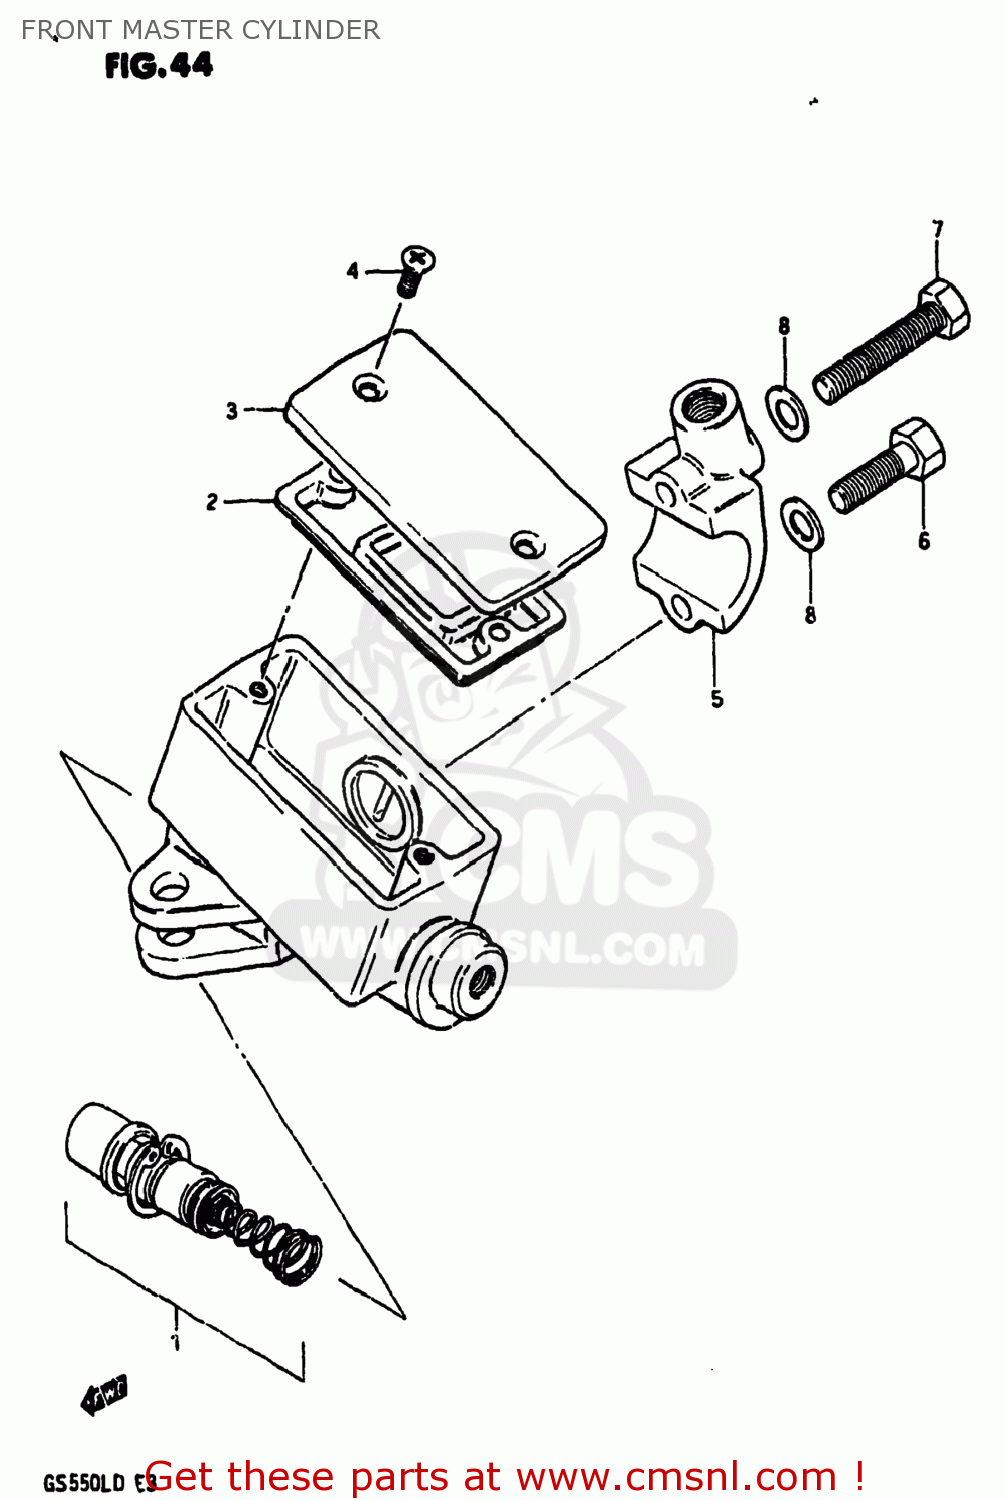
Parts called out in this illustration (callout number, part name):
1	CUP SET,MASTER CYLINDER
2	3
3	CAP
4	SCREW
5	HOLDER
6	BOLT
7	BOLT
8	WASHER
